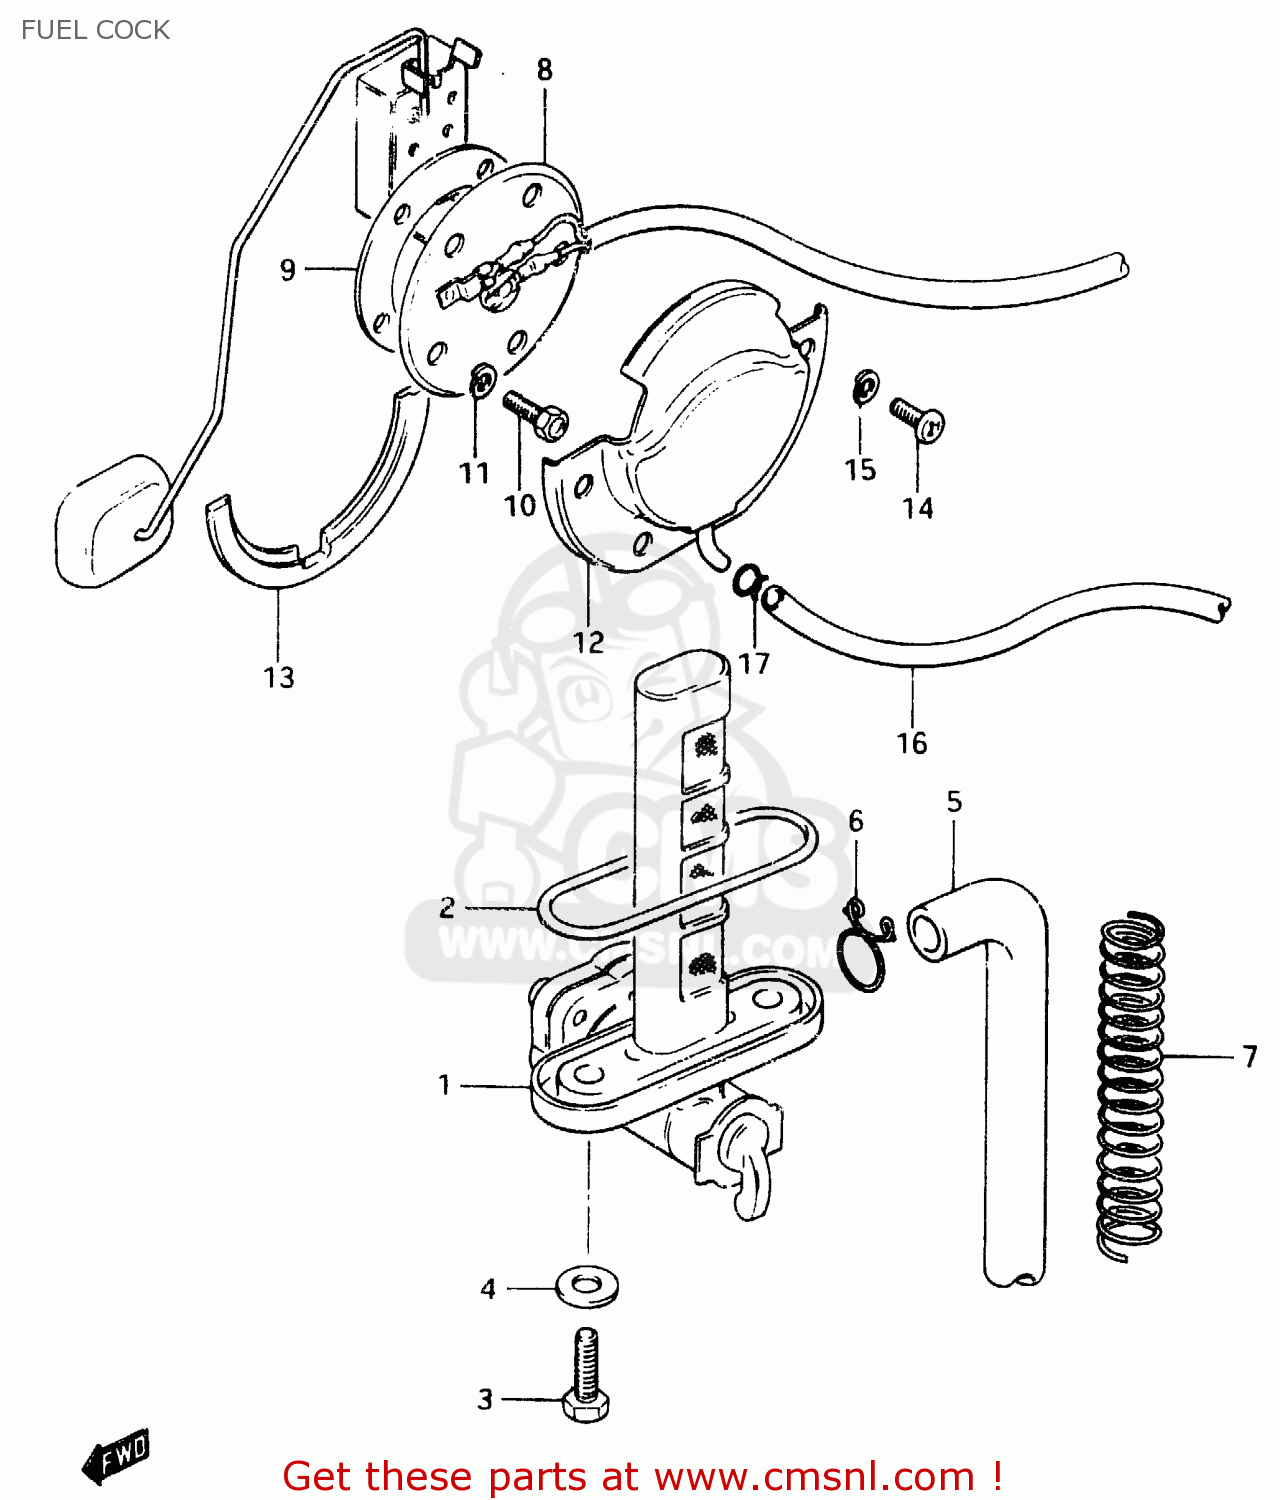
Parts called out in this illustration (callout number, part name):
1	COCK ASSEMBLY,FUEL
2	O RING
3	BOLT(6X20)
4	GASKET
5	HOSE
6	CLIP
7	SPRING
8	GAUGE, FUEL LEVER
9	GASKET,FUEL LEVEL GAUGE (NAS)
10	BOLT
11	LOCK WASHER
12	PLATE,FUEL DRAIN
13	GASKET (NAS)
14	SCREW
15	LOCK WASHER
16	HOSE,FUEL
17	CLIP
